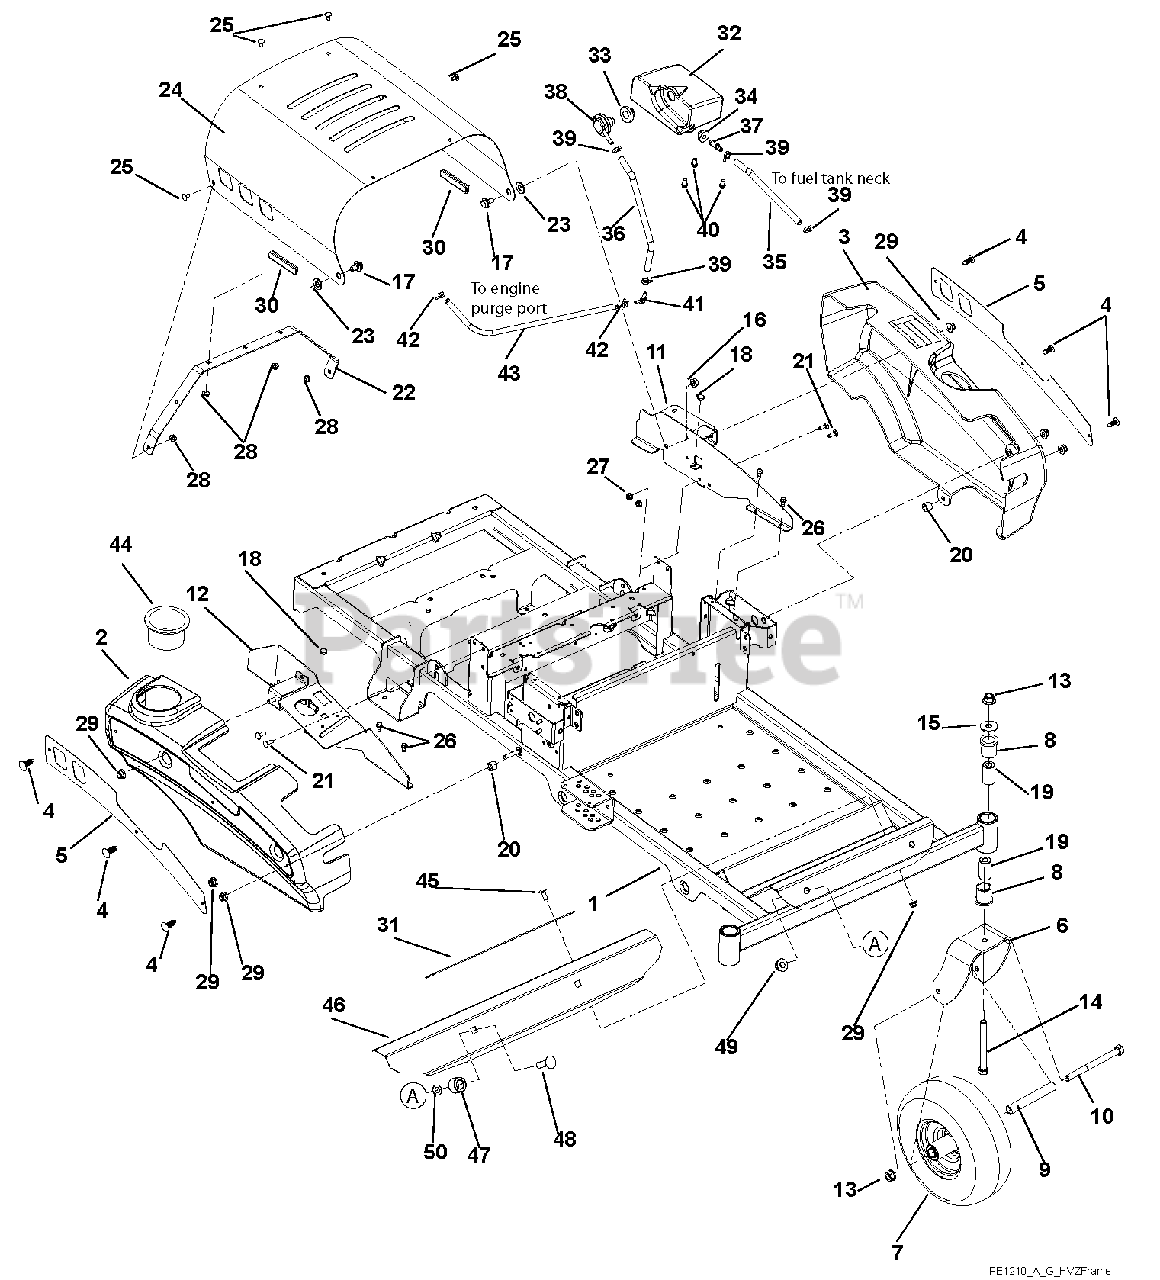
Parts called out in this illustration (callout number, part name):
1	Weldment, Frame
2	Fender, Right Hand
3	Fender, Left Hand
4	Rivet, Nylon
5	Plate, Fender
6	Fork, Caster
7	Wheel/Tire Assembly, 11.0 x 4.0 x 5.0
8	Bushing, Flange 1.00 x 1.25 x 1.50 x 1.50
9	Spacer, Wheel
10	Bolt, Hex .50-13 x 6.50
11	Weldment, Left Hand Fender Mount
12	Weldment, Right Hand Fender Mount
13	Nut, Locking, Top, Flange .50-13
14	Bolt, Hex .50-13 x 5.00
15	Washer, Flat Steel .511 x 1.441 x .125
16	Nut, Locking, Top, Flange .38-16
17	Bolt, Shoulder .375-16 x .135
18	Bumper Grommet .125 x .250 Diameter
19	Spacer, Caster
20	Bushing, Sleeve .391 x .688 x .52
21	Bolt, Round Head Square Neck .25-20 x .75
22	Hood Brace
23	Washer, Flat, Nylon .52 x 1.00 x .08
24	Hood, ZT
25	Bolt, Round Head Square Neck .25-20 x .50
26	Nut, Locking Toop Flange .25-20
27	Screw, Tapping .25-20 x .50 Hex Washer Head Thread
28	Nut, Locking Top Flange .25-20
29	Nut, Locking, Nylon, Flange .31-18
30	Edging, Clutch Paddle - 2.00"
31	Grip, Adhesive (1" x 16" BLK)
32	Tank, ZT/Waw Fuel Exp. (Serial Number 2500 – up)
33	Grommet, Remote Vent Nitrile (Serial Number 2500 – up)
34	Bushing, Flange .375 x 1.062 x .625 (Serial Number 2500 – up)
35	Hose, .25 Low-Perm Bulk Gas (7.00 inches) (Serial Number 2500 – up)
36	Hose, .25 Low-Perm Bulk Gas (27 inches) (Serial Number 2500 – up)
37	Fitting, Straight Fuel (Serial Number 2500 – up)
38	Vent, Roll-Over (.25" ID Hose) (Serial Number 2500 – up)
39	Clamp, Hose Wire .490/.510 x .116 (Serial Number 2500 – up)
40	Bolt, Serrated Hex Flange Washer Head .312-18 x .50 (Serial Number 2500 – up)
41	Fitting, 3/16 x 1/4 90° Vac (Serial Number 2500 – up)
42	Clamp, Hose, Spring .188 (Serial Number 2500 – up)
43	Hose, .188 Low-Perm Bulk Gas (7 inches) (915146) (Serial Number 2500 – up)
44	Cupholder, Snap-In, 3.75 OD
45	Bolt, Round Head Square Neck .31-18 x .75
46	Foot Rest
47	Tube, Upper Control Pivot
48	Bolt, Round Head Square Neck .50-13 x 1.75
49	Nut, Locking Nylon Flange .50-13
50	Nut, Push .50
